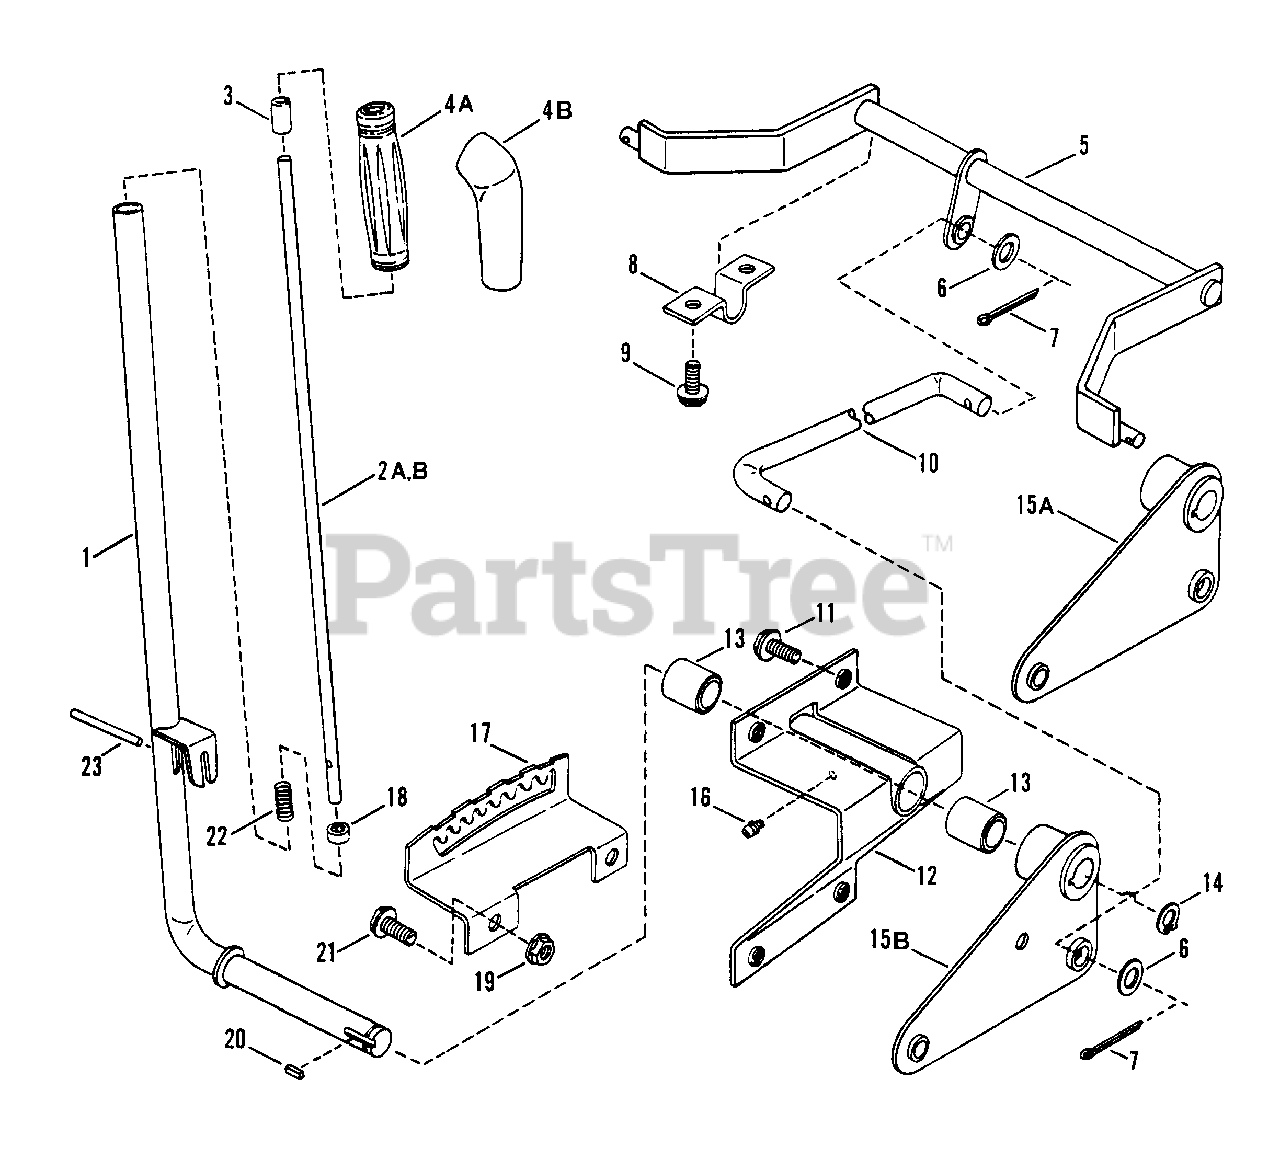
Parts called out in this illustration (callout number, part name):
1	ARM, Implement Lift Lever
2A	ROD, Lift Lever
2B	ROD, Lift Lever
3	CAP, Lift Release
4A	GRIP, Handle
4B	GRIP, Handle
5	ARM, Rear Lift
6	WASHER, 1/2 SAE
7	COTTER-PIN, 1/8 x 1"
8	BRACKET, Hanger
9	SCREW, 3/8C x 1/2" Hex Washer, Self-Tapping
10	LIFT-ROD
11	SCREW, 5/16C x 5/8" Self-Tapping
12	PIVOT ASSM'Y., Lift Lever
13	BEARING, Sleeve
14	RING, Retaining
15A	LEVER-ARM
15B	LEVER-ARM
16	LUBE FITTING, Straight (press-fit for .187 dia. Hole)
17	QUADRANT, Lift Lever
18	PLUG, Rod
19	NUT, 3/8C Hex Lock
20	KEY, 1/4 x 1" Square
21	BOLT, 3/8C x 3/4" Hex Flange Lock
22	SPRING, Lift Handle
23	PIN, 3/16 x 2"
